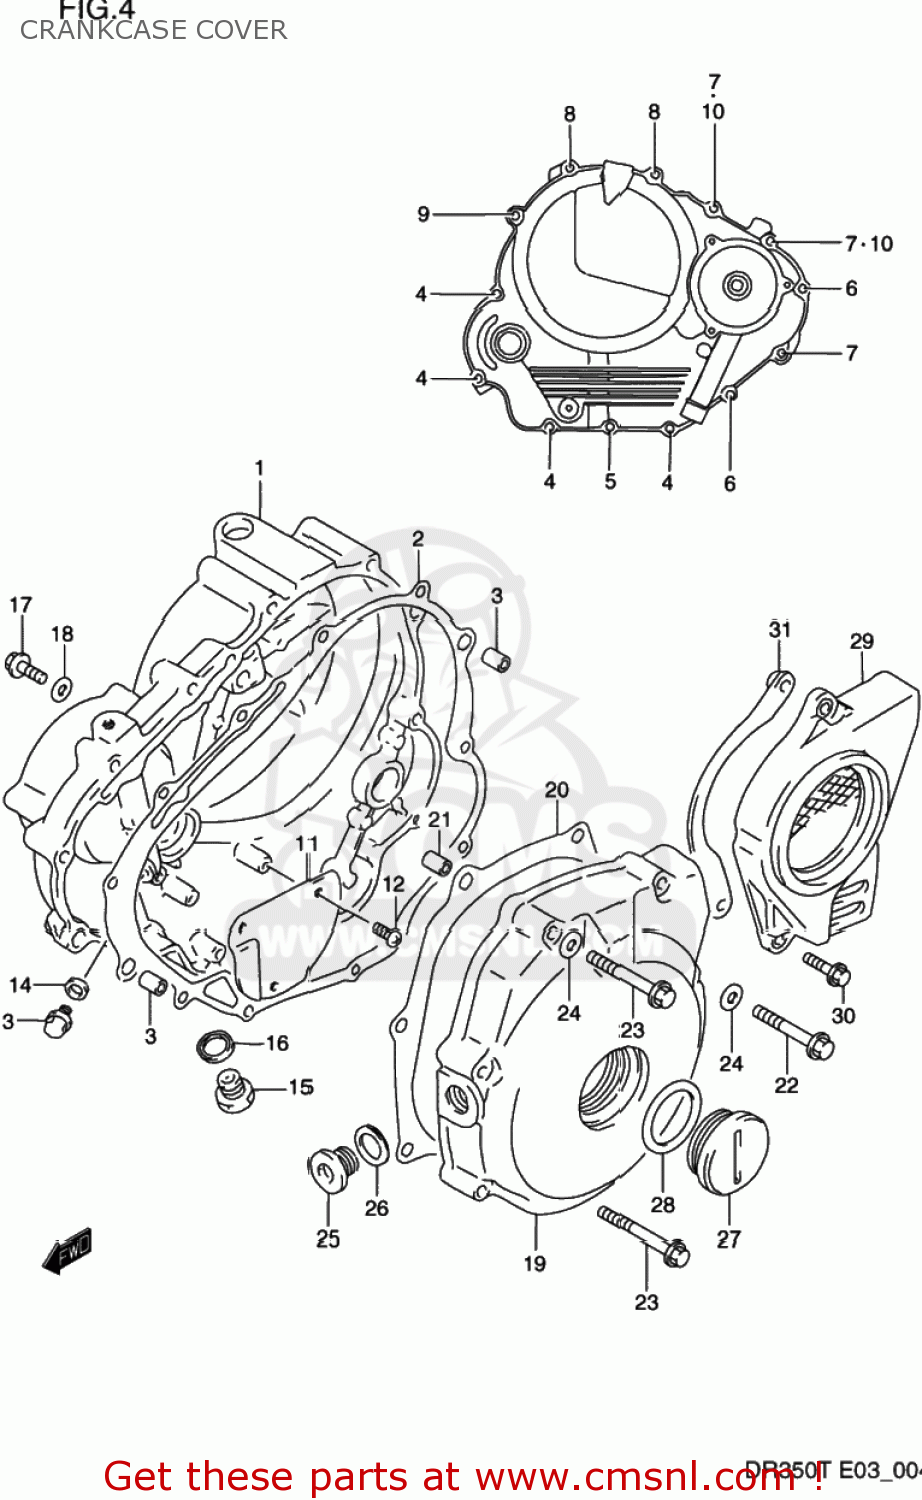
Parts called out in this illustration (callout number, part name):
1	COVER,CLUTCH
2	GASKET,CLUTCH COVER (NAS)
3	PIN
4	BOLT
5	BOLT
6	BOLT
7	BOLT
8	BOLT
9	BOLT
10	GASKET(5.8X13X1.2) (NAS)
11	SEPARATOR,OIL RETURN
12	SCREW
13	BOLT(6X8)
14	GASKET(6.2X11X1).2 (NAS)
15	PLUG,14X12
16	GASKET(14X19.2X2) (NAS)
17	SCREW (6X10)
18	GASKET(5.8X13X1.2) (NAS)
19	COVER,MAGNETO
20	GASKET,MAGNETO COVER (NAS)
21	PIN
22	BOLT
23	BOLT
24	GASKET(5.8X13X1.2) (NAS)
25	PLUG,14X12
26	GASKET(13.8X18.8X4.8) (NAS)
27	PLUG
28	O RING(D:3.1,ID:32.7)
29	COVER,ENGINE SPROCKET
30	BOLT
31	PLATE,FR CHAIN GUIDE
